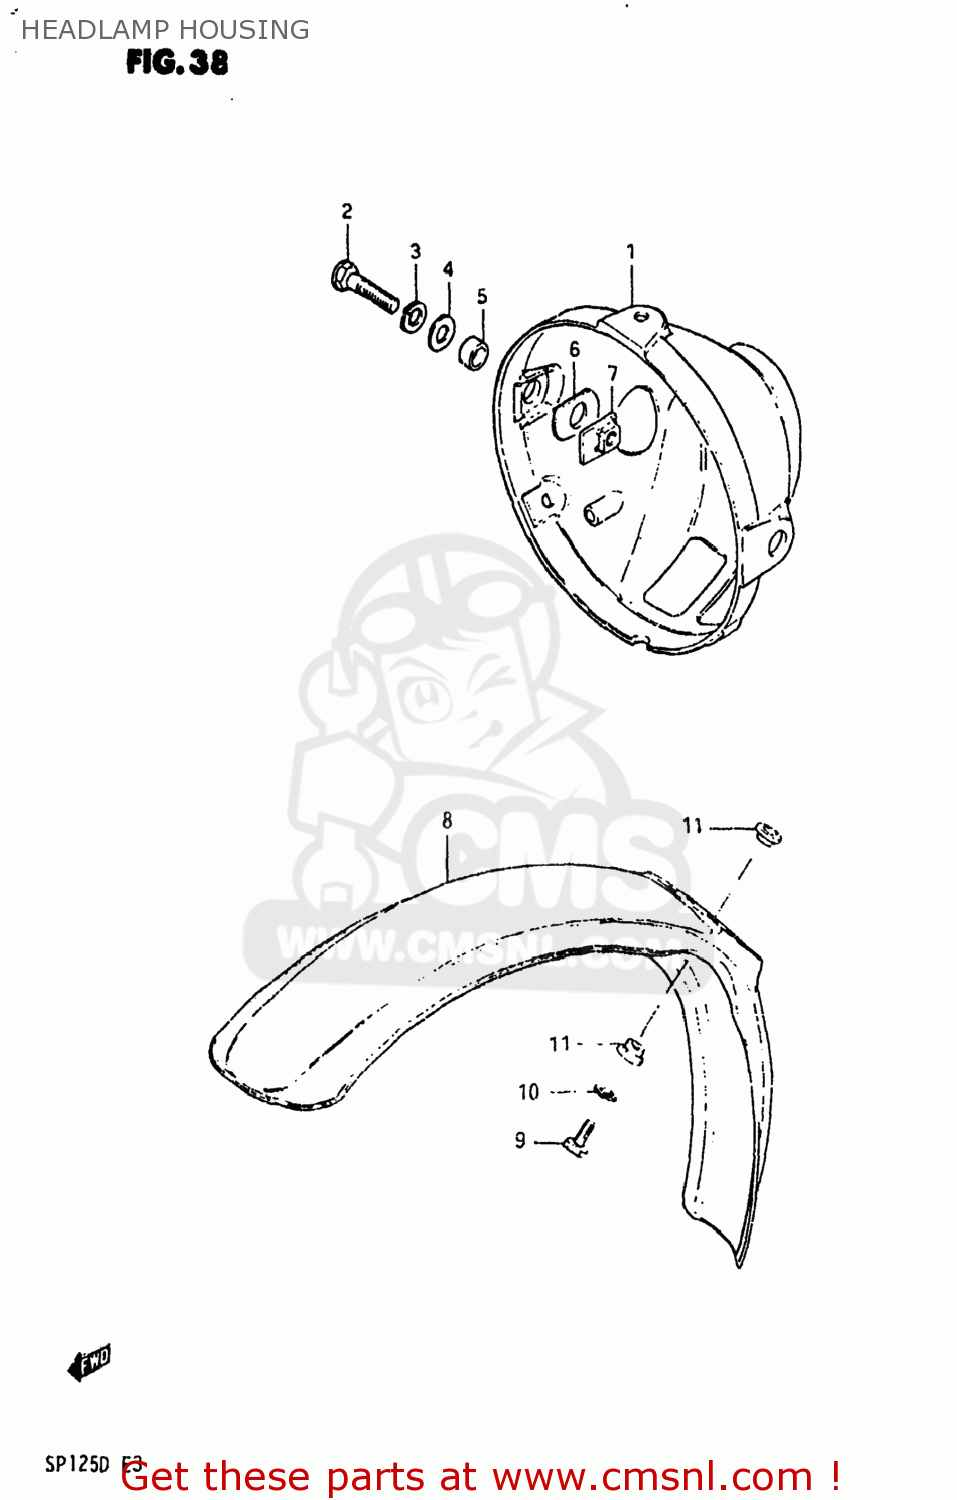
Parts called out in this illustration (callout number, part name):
1	HOUSING,HEADLAMP
2	BOLT
3	LOCK WASHER
4	WASHER
5	SPACER (8.8X12X7)
6	CUSHION
7	PLATE,HEADLAMP HOUSING
8	FENDER,FRONT
9	BOLT, UPPER
10	LOCK WASHER
11	SPACER
